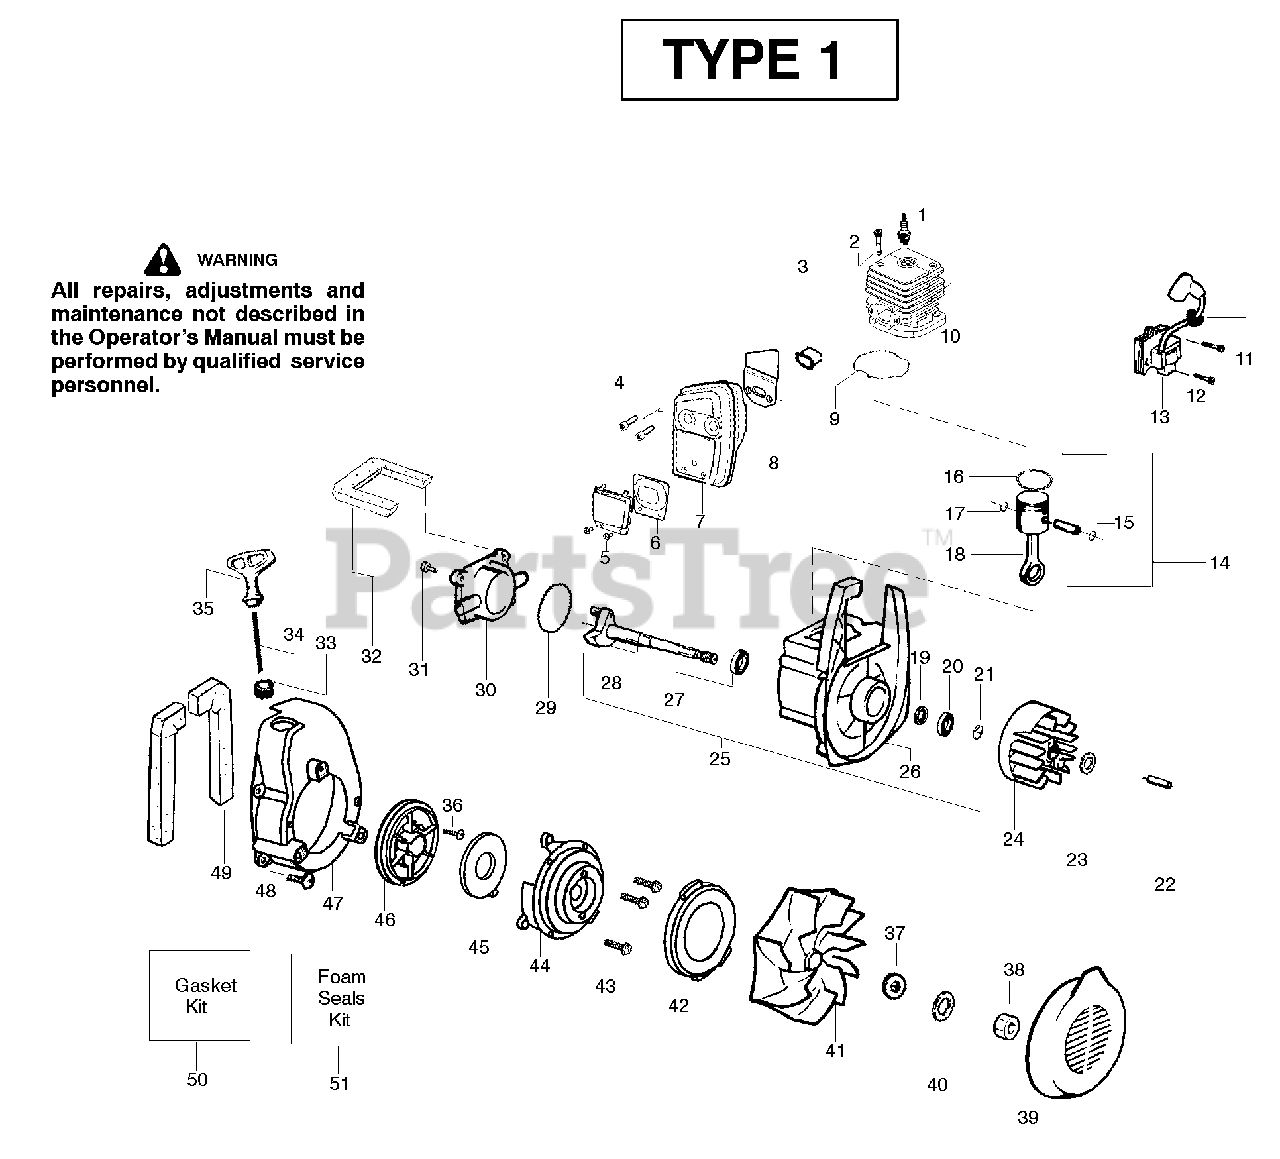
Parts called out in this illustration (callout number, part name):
1	Spark Plug (RCJ-6Y)
3	Insulator-Heat
4	Screw-Muffler-Internal
6	Kit-Spark Screen
7	Kit-Muffler
8	Gasket-Baffle (kit)
9	Gasket-Cylinder (kit)
10	Kit-Cylinder
11	Grommet-Ign. Module
12	Screw-Ignition Module
13	Ignition Module
14	Kit-Piston/Rod
15	Kit-Piston
16	Piston Ring
17	Retainer-Piston Pin
18	Assy-Connecting Rod
20	Bearing-Outer
21	Retainer Ring-C'chaft
22	Spacer-Flywheel
24	Assy-Flywheel
25	Assy-Crankcase/Crank shaft
26	Assy-Crankcase
27	Bearing-Inner
28	Assy-Crankshaft
29	O-ring-C/case (kit)
30	Cover-Crankcase
31	Screw
32	Foam-219mm (kit)
33	Eyelet-Flange
34	Kit-Rope
35	Handle-Starter
36	Screw-Rope
37	Washer-Belleville
39	Inlet Door
41	Kit-Impeller Assy.
42	Seal-Ring
44	Housing-Pulley
45	Spring-Starter
46	Kit-Starter Pulley
47	Fan Housing
48	Screw
49	Foam-182mm (kit)
50	Kit-Gasket
51	Kit-Foam Seals
